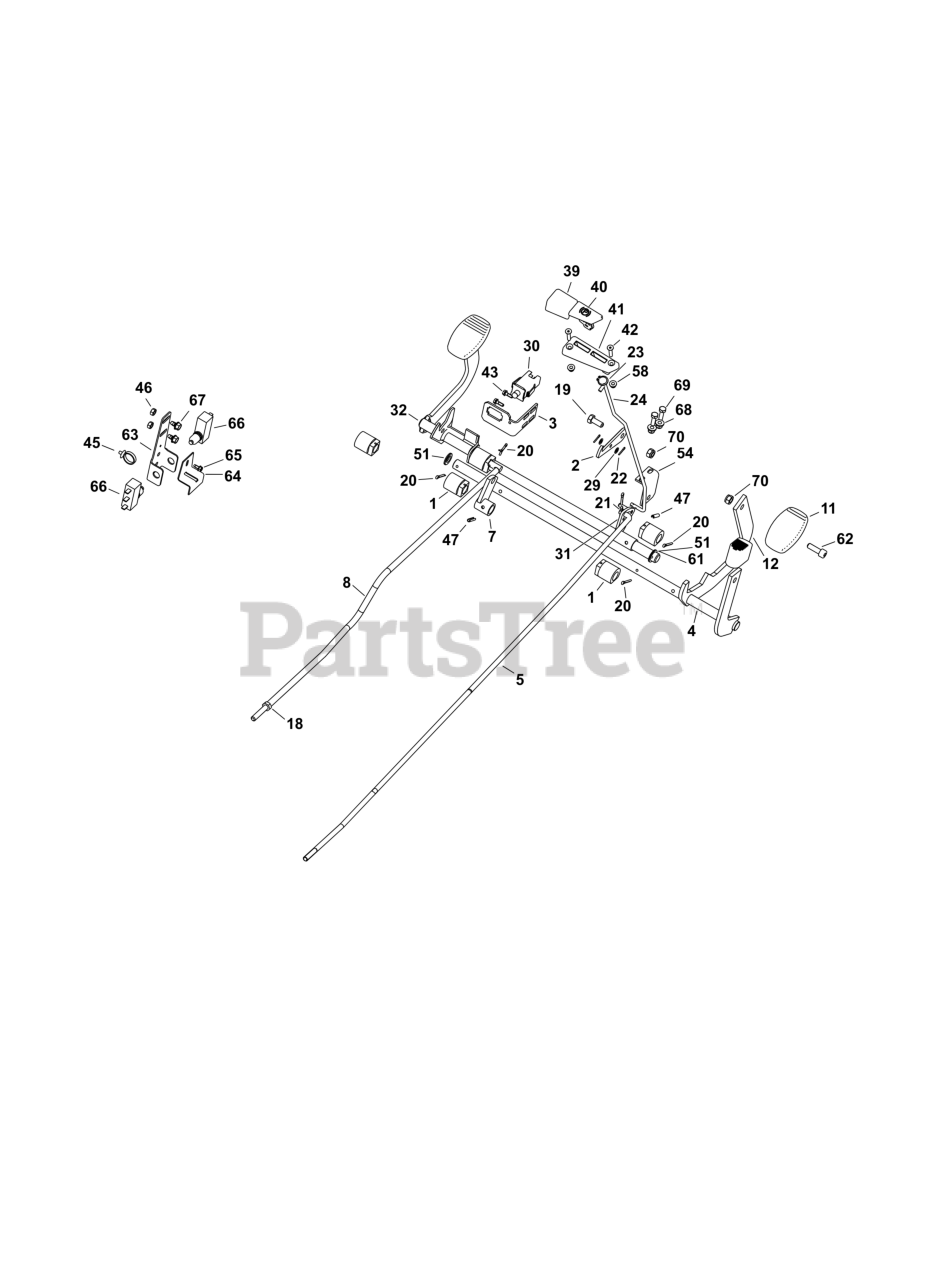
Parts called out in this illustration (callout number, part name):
5	ROD, Brake
11	PAD, Rubber
12	PAD, Foot
24	ROD, Brake
32	BRAKE, Pedal
66	MICROSWITCH
